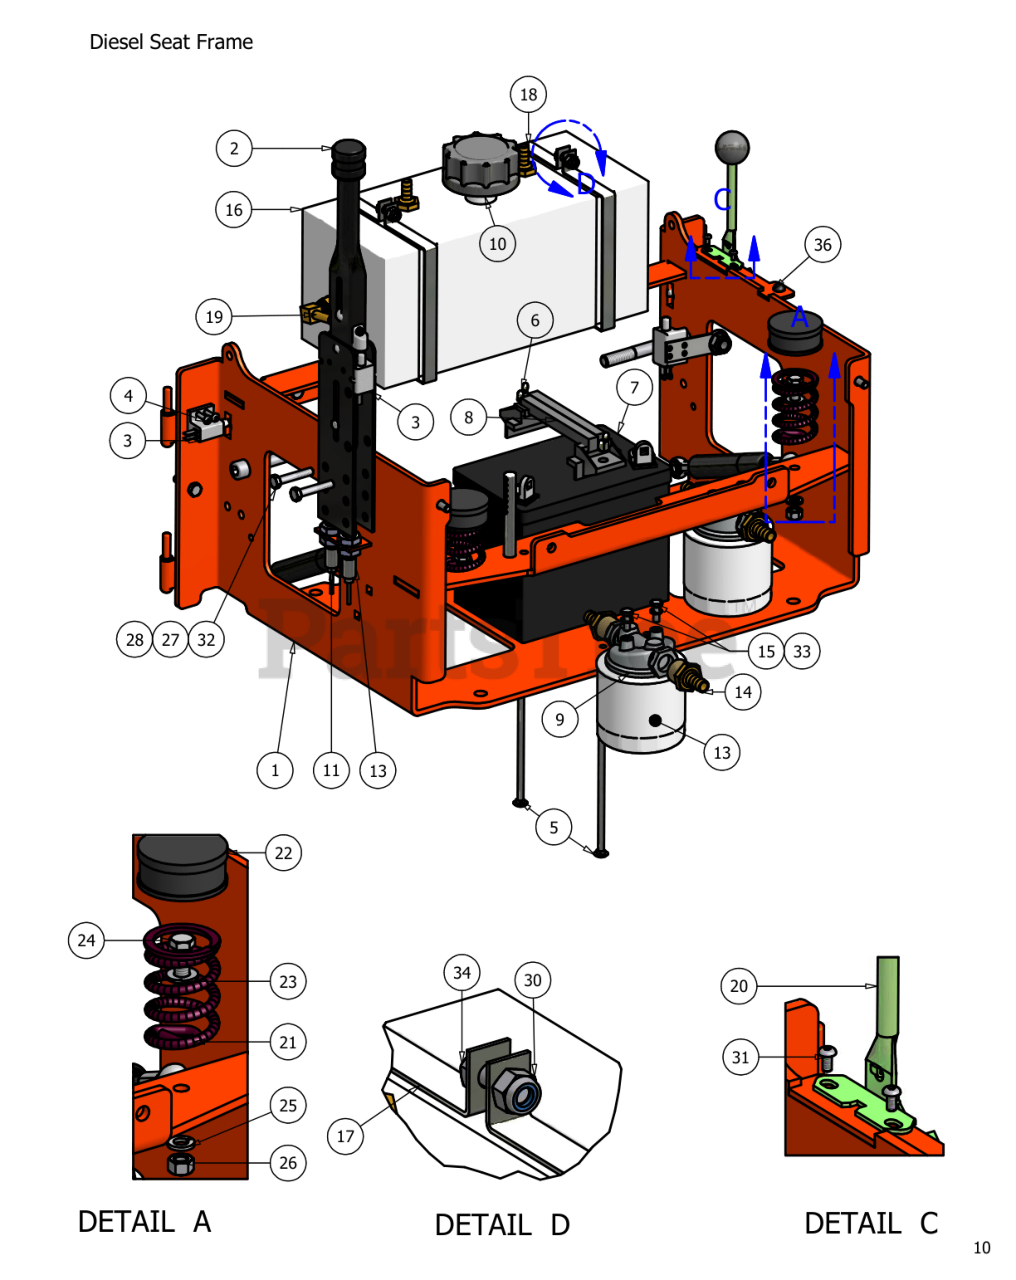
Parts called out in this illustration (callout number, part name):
1	Seat Frame
2	Brake Lever
3	Brake Handle Switch
4	1024 x 1" Bolt
5	9" Stove Bolt for Diesel (Aos gets 8")
6	1/4" Wing Nut
7	Diesel Battery
8	Battery hold-down
9	Filter Head
10	Hydraulic Tank Cap
11	Short Brake Cable
12	Long Brake Cable
13	Hydraulic Filter
14	1/2" x 1/2" Filter Head Fitting
15	1/4" x 3/4" Hex Bolt
16	Hydraulic Tank
17	Hydraulic Tank Strap
18	3/8" X 3/8" Hose Barb
19	1/2" x 1/2" Filter Head Fitting (90 Degree)
21	Seat Spring
22	1 1/2" Spring Cap Cover
23	3/8" Flat Washer
24	3/8" x 1 1/2" Hex Bolt
25	3/8" Lock Washer
26	3/8" Hex Nut
27	5/16" Lock Washer
30	5/16" Nylock Nut
31	1024 X 5/8" Buttonhead Bolt
32	5/16" x 1 3/4" Hex Bolt
33	1/4" Lock Washer
34	5/16" x 3/4" Hex Bolt
35	Piezo Buzzer
36	Momentary Start Switch- Diesel
